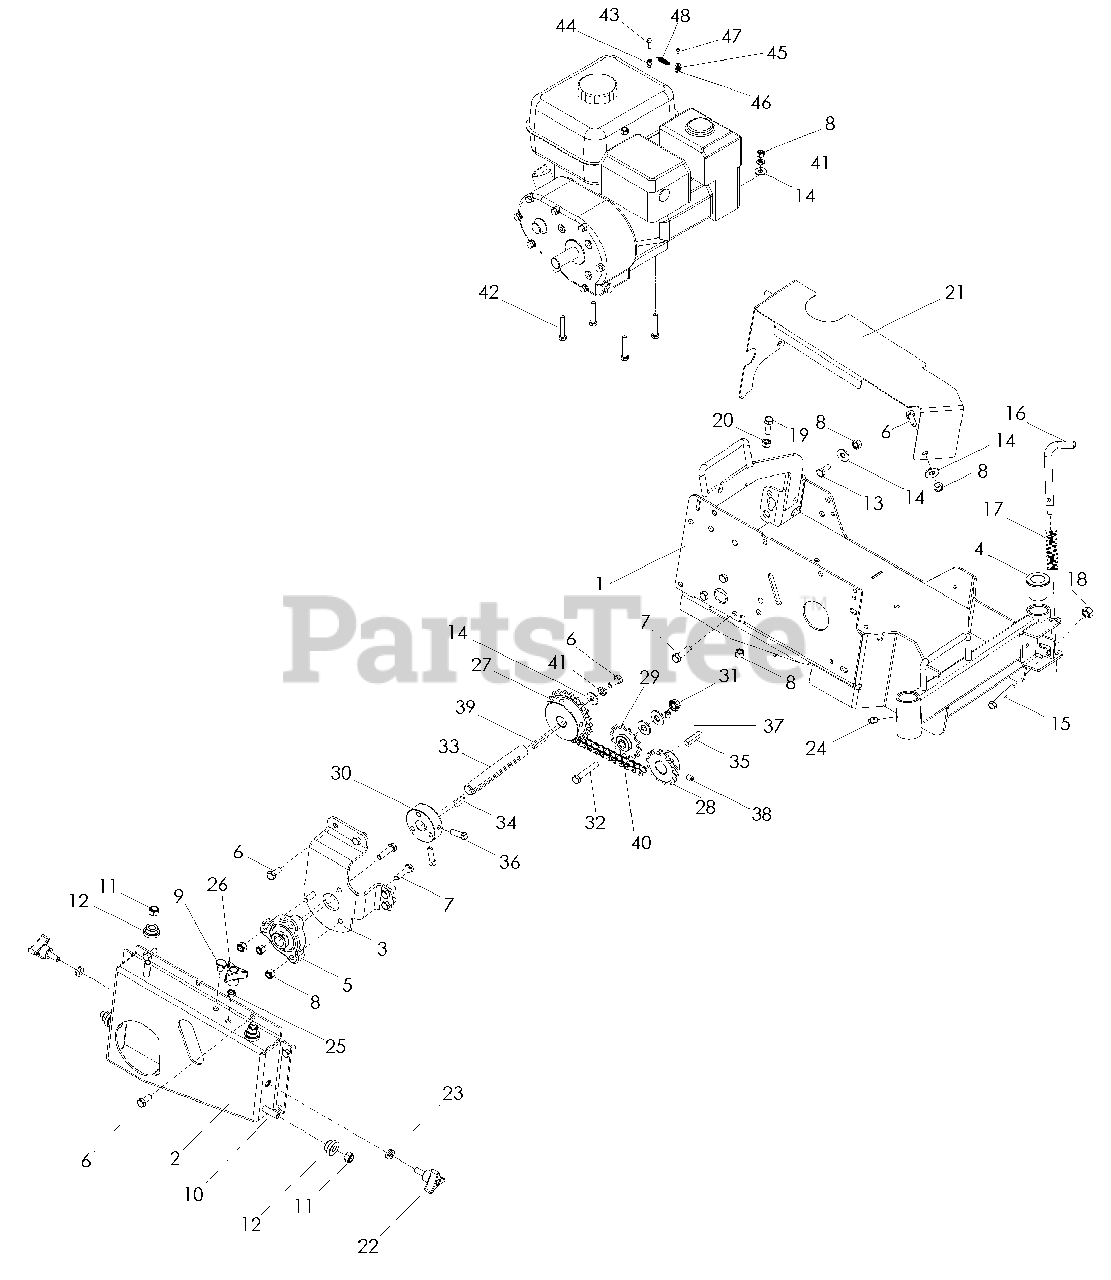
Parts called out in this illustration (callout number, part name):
1	FRAME, ORANGE
2	COVER, CHAIN
3	SUPPORT, BEARING
4	BUSHING, FLANGED
5	BEARING, FLANGED
6	HCS 5/16-18 x 3/4
7	HCS 5/16-18 x 1 1/4
8	NUT 5/16-18 HEX NYLOC
9	OIL CAP 3/8
10	HCS 3/8-16 x 1 1/4
11	NUT 3/8-16 HEX NYLOC
13	HCS 5/16-18 x 3/4
14	WASHER 5/16 STD FLT
15	HCS 1/4-20 x 1 3/4
16	PIN, SPRING
17	SPRING, COMPRESSION
18	NUT 1/4-20 HEX NYLOC
19	HCS 5/16-18 x 1
20	NUT 5/16-18 HEX
22	KNOB W/STUD
23	WASHER 5/16 SEALING
24	ZERK 1/8 NPT
25	NUT 5/16-18 HEX JAM
26	KNOB 5/16-18 NYLOC
27	SPROCKET W/KEY
28	SPROCKET, ENGINE
29	SPROCKET ASSM, IDLER
30	HUB, MOUNTING
31	NUT 3/8-16 HEX WHIZLK
32	HCS 3/8-16 x 1 3/4
34	KEY 1/4 SQ x 3/4
35	KEY 7mm SQ x 33mm
36	SETSCREW 5/16-18 x 1
37	WASHER 3/8 STD FLT
38	SETSCREW 5/16-18 x 3/8
39	KEY 3/16 SQ x 1 1/4
40	CHAIN, TRANSMISSION
41	WASHER 5/16 SPLT LOCK
42	HCS 5/16-18 x 1 3/4
43	HCS M5-0.8 x 16mm GR 8.8
44	NUT 5MM-.8 HEX
45	CLAMP, THROTTLE CABLE
46	E-RING CLIP
47	SCREW #8-32 x 1/4
48	SPRING, THROTTLE
